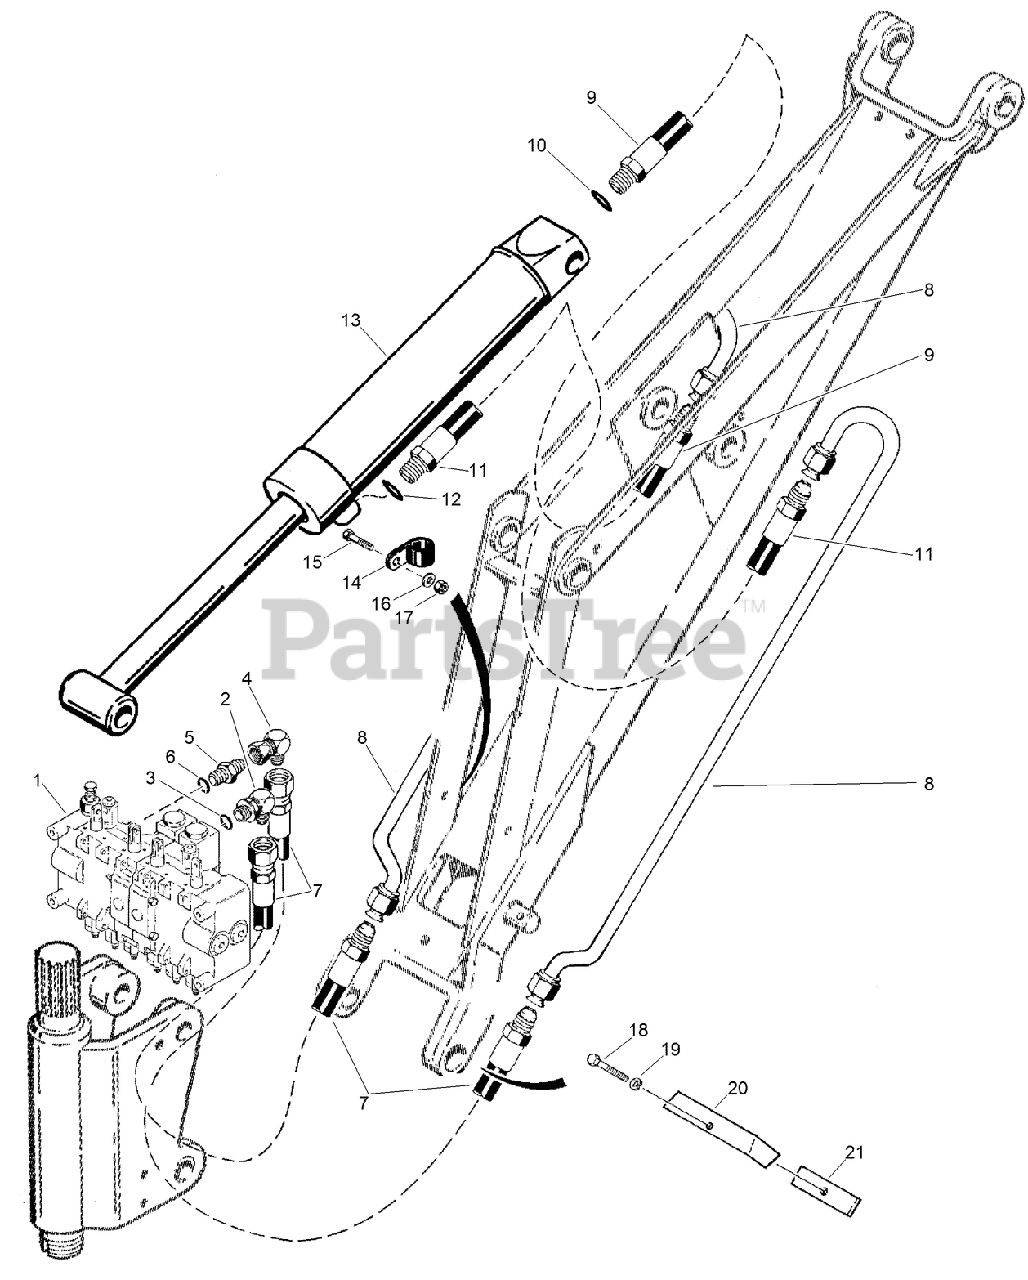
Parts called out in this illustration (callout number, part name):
1	VALVE-Backhoe, w/Special Low Leak Spools
2	ELBOW-90 Adj 37FL, 1/2 Tube
3	O-RING
4	ELBOW-90 Swivel 37FL 1/2 Tube
5	CONNECTOR-Str Thd 1/2, 37FL-ORB 1/2
6	O-RING
7	HOSE-1225 mm (48-1/4 inch) long, control valve to tube
8	TUBE-intermediate, to boom cylinder
9	HOSE-381 mm (15 inch) long, to closed end of boom cylinder
10	O-RING
11	HOSE-889 mm (35 inch) long, to rod end of boom cylinder
12	O-RING
13	CYLINDER-Backhoe
14	CLAMP-Tube
16	WASHER-FLAT
17	NUT-Prev Trq 1/4 GRA CAD NONDIR
18	BOLT-Hex Hd 0.312 x 2.00 GR8 ZND
19	WASHER-Lock, 5/16 inch
20	BRACKET-Hose Retainer
21	SPACER-tube
